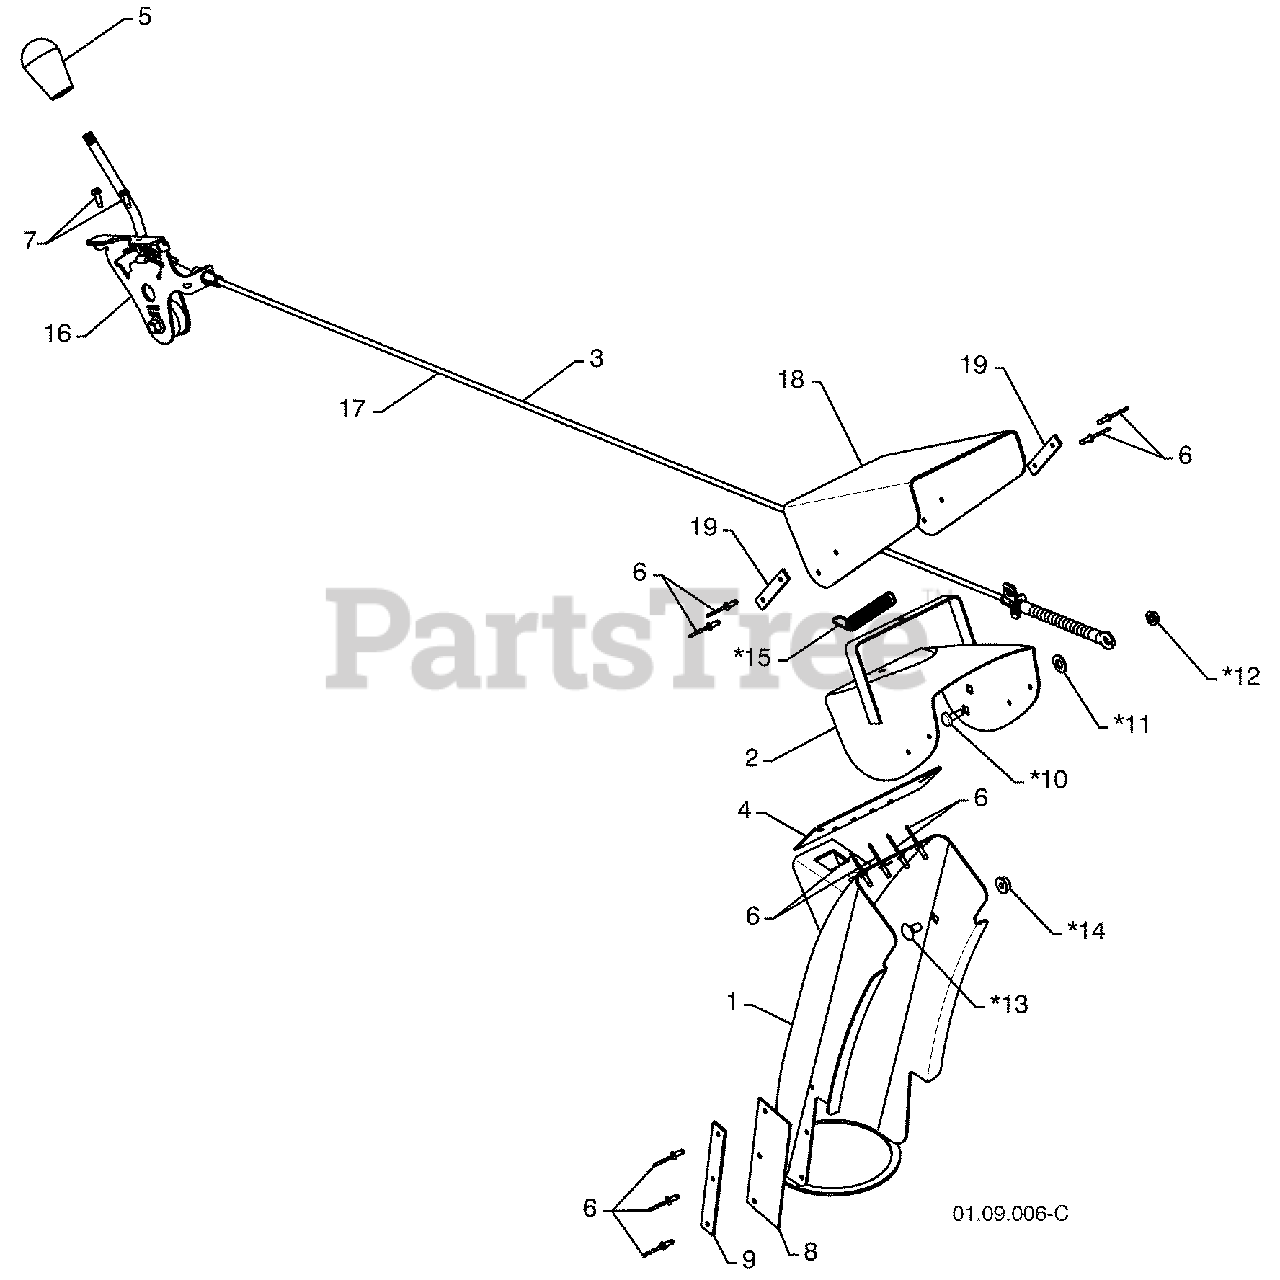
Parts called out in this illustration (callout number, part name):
1	CHUTE WELDMENT
2	DEFLECTOR WELDMENT
3	DEFLECTOR CONTROL ASSEMBLY
4	DEFLECTOR SEAL
5	KNOB BLACK
7	SCREW 10-24 X .625
8	CHUTE SNOW SHIELD
9	SHIELD RETAINER STRAP
10	SHOULDER BOLT 1/4-20 X .375
11	PLASTIC WASHER
12	NUT 1/4-20
13	CARRIAGE BOLT 3/8-16 X .625
14	NUT 5/16-18
15	DEFLECTOR SPRING
16	(SERVICE PART) DEFLECTOR CONTROL
17	(SERVICE PART) DEFLECTOR CABLE GRAY
18	DEFLECTOR SHIELD
19	DEFLECTOR SHIELD STRAP
